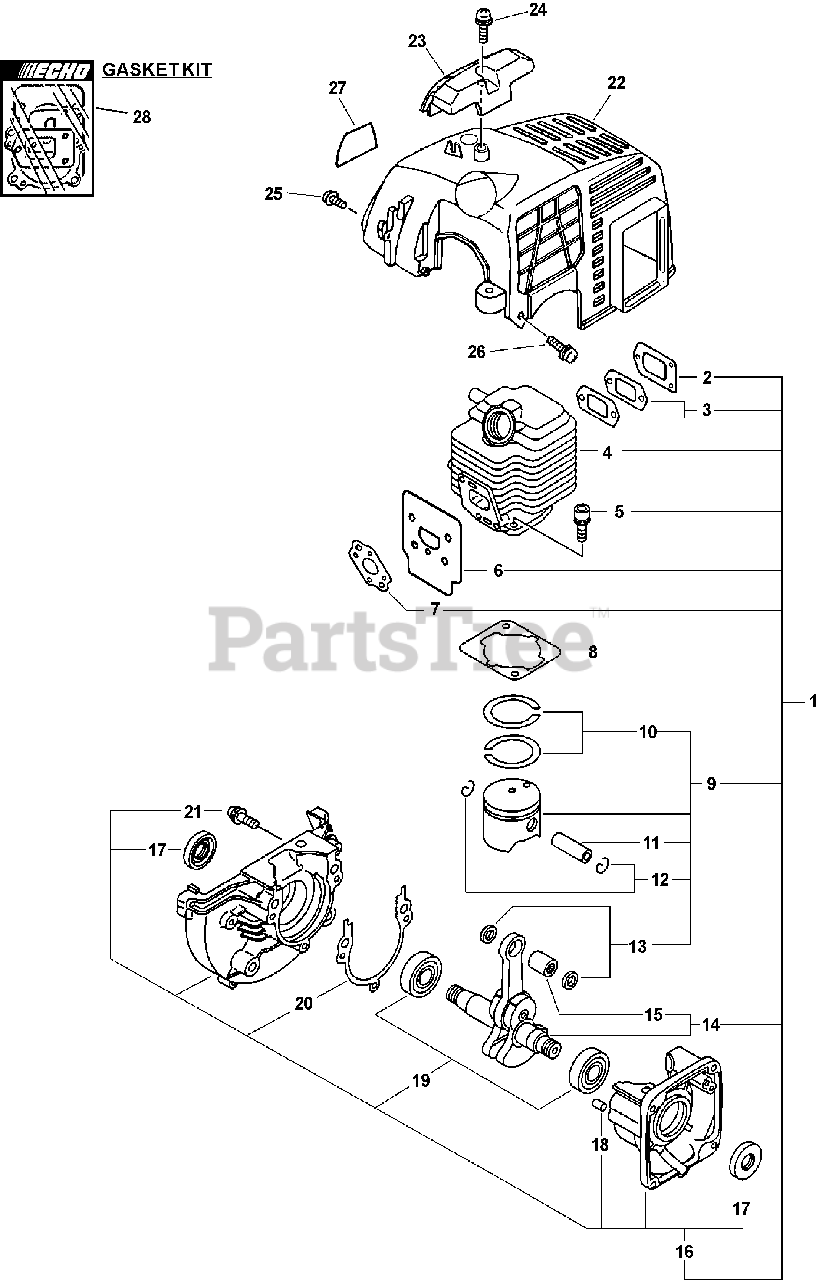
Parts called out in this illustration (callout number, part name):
1	SHORT BLOCK ES-2100;PB-2100
2	GASKET, EXHAUST
3	GASKET, EXHAUST
4	CYLINDER
5	BOLT 5×22
6	HEAT SHIELD, INTAKE
7	GASKET, INTAKE
8	GASKET, CYLINDER
9	PISTON KIT
10	RING, PISTON
11	PIN, PISTON 8
12	RING, SNAP
13	WASHER, THRUST
14	CRANKSHAFT ASSY
15	BEARING, NEEDLE 8
16	CRANKCASE KIT
17	SEAL, OIL 12
18	PIN, LOCATING 4
19	BEARING, BALL - 6201 C3
20	GASKET, CRANKCASE
21	BOLT 5×28
22	COVER, ENGINE - GRAY
23	GUARD, TOP - GRAY
24	SCREW 5×16
25	BOLT 4×16
26	SCREW 4×12
27	LABEL, MODEL
28	GASKET KIT
